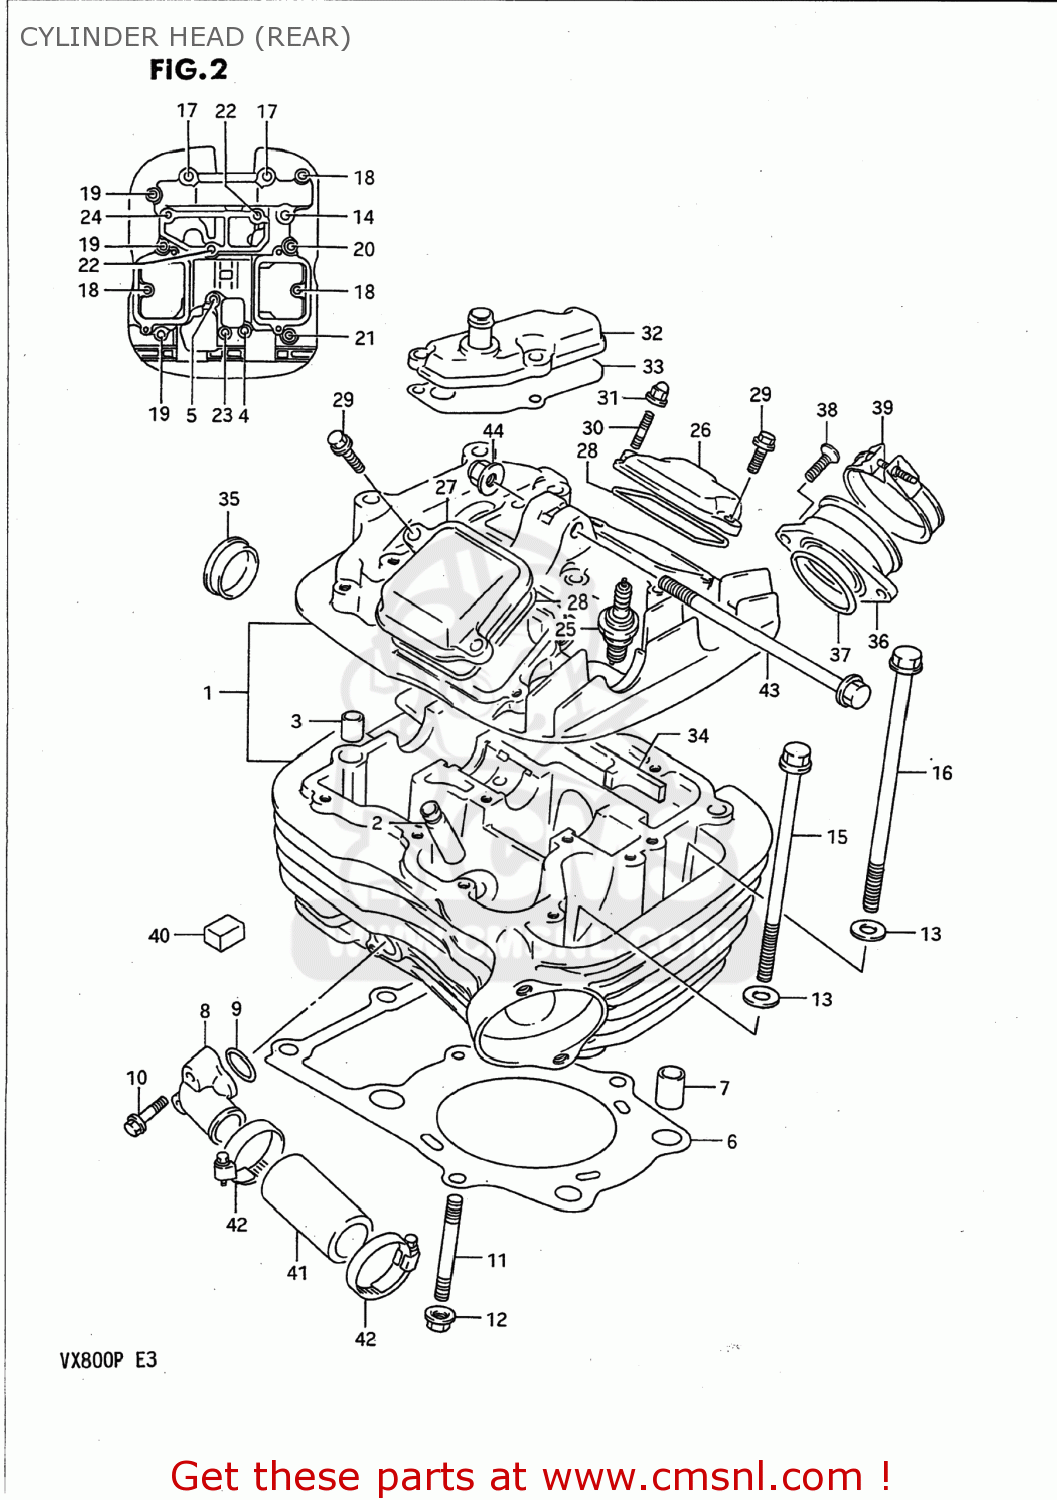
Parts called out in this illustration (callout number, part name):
1	HEAD ASSEMBLY,CYLINDER,REAR
2	GUIDE,VALVE
3	PIN(11X14)
4	BOLT(6X50)
5	BOLT(6X55)
6	GASKET,CYLINDER HEAD RR (NAS)
7	PIN
8	UNION,CYLINDER HEAD WATER
9	O RING(D:2.4,ID:17.8)
10	BOLT
11	BOLT,STUD
12	NUT
13	WASHER(10.5X22X2.3)
14	BOLT(8X140)
15	BOLT(10X155)
16	BOLT(10X165)
17	BOLT
18	BOLT 6X25
19	BOLT
20	BOLT
21	BOLT
22	BOLT(6X55)
23	BOLT(6X50)
24	BOLT 6X20
25	PLUG,SPARK(DPR8EA-9)
26	CAP,INSP.INT
27	CAP,INSPECTION,EXHAUST
28	GASKET,INSPECTION CAP (NAS)
29	BOLT
30	STUD 6X16
31	NUT
32	COVER,BREATHER
33	GASKET,BREATHER COVER (NAS)
34	PLATE,HEAD COVER RR
35	PLUG(OD:30)
36	PIPE COMP,INTAKE,REAR
37	O-RING (D:2.4 ID:39.7)
38	SCREW
39	CLAMP,PIPE
40	PAD
41	HOSE,CYLINDER HEAD JOINT
42	CLAMP
43	BOLT(8X135)
44	NUT (8MM)
